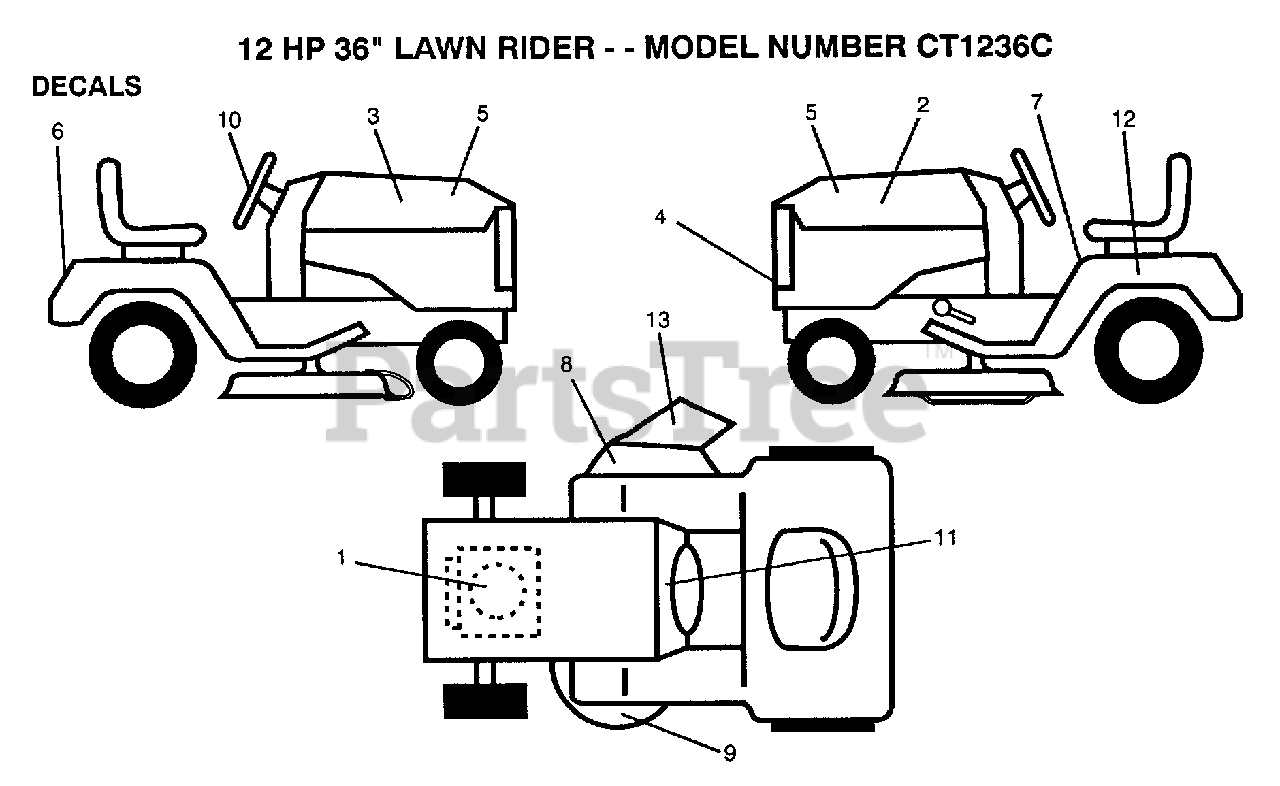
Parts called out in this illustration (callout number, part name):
1	DECAL.B&S.272129
2	"DECAL,STP HD LH"
3	"DECAL,STP HD RH"
4	GRILL DECAL
5	"DECAL,HOOD"
6	FENDER DECAL
7	DECAL
8	DECAL WARNING
9	DECAL YT
10	"DECAL,STR WHL"
12	DECAL
13	DECAL WARNING
